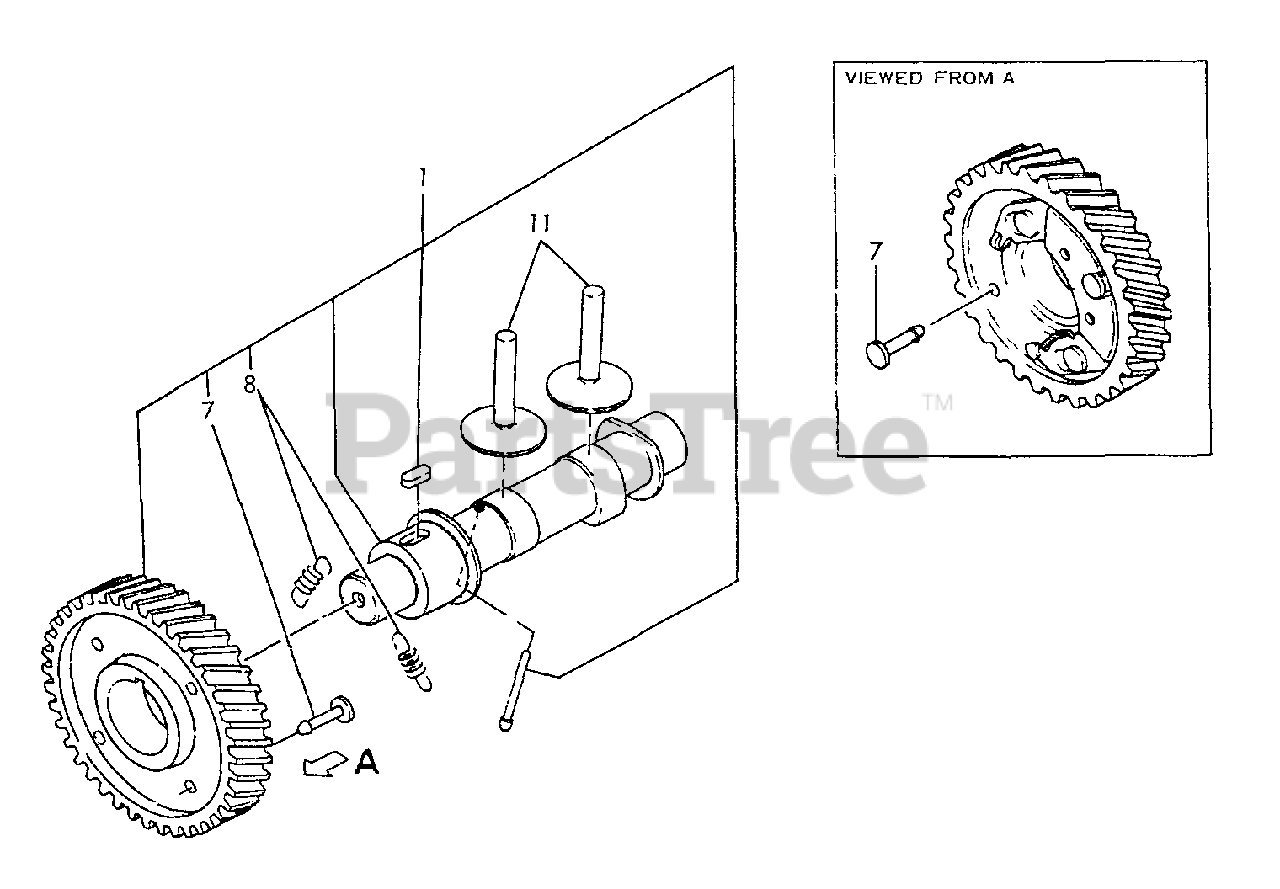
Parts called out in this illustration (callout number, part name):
1	CAMSHAFT ASSY
7	PIN, GUIDE - B
8	SPRING
11	TAPPET
